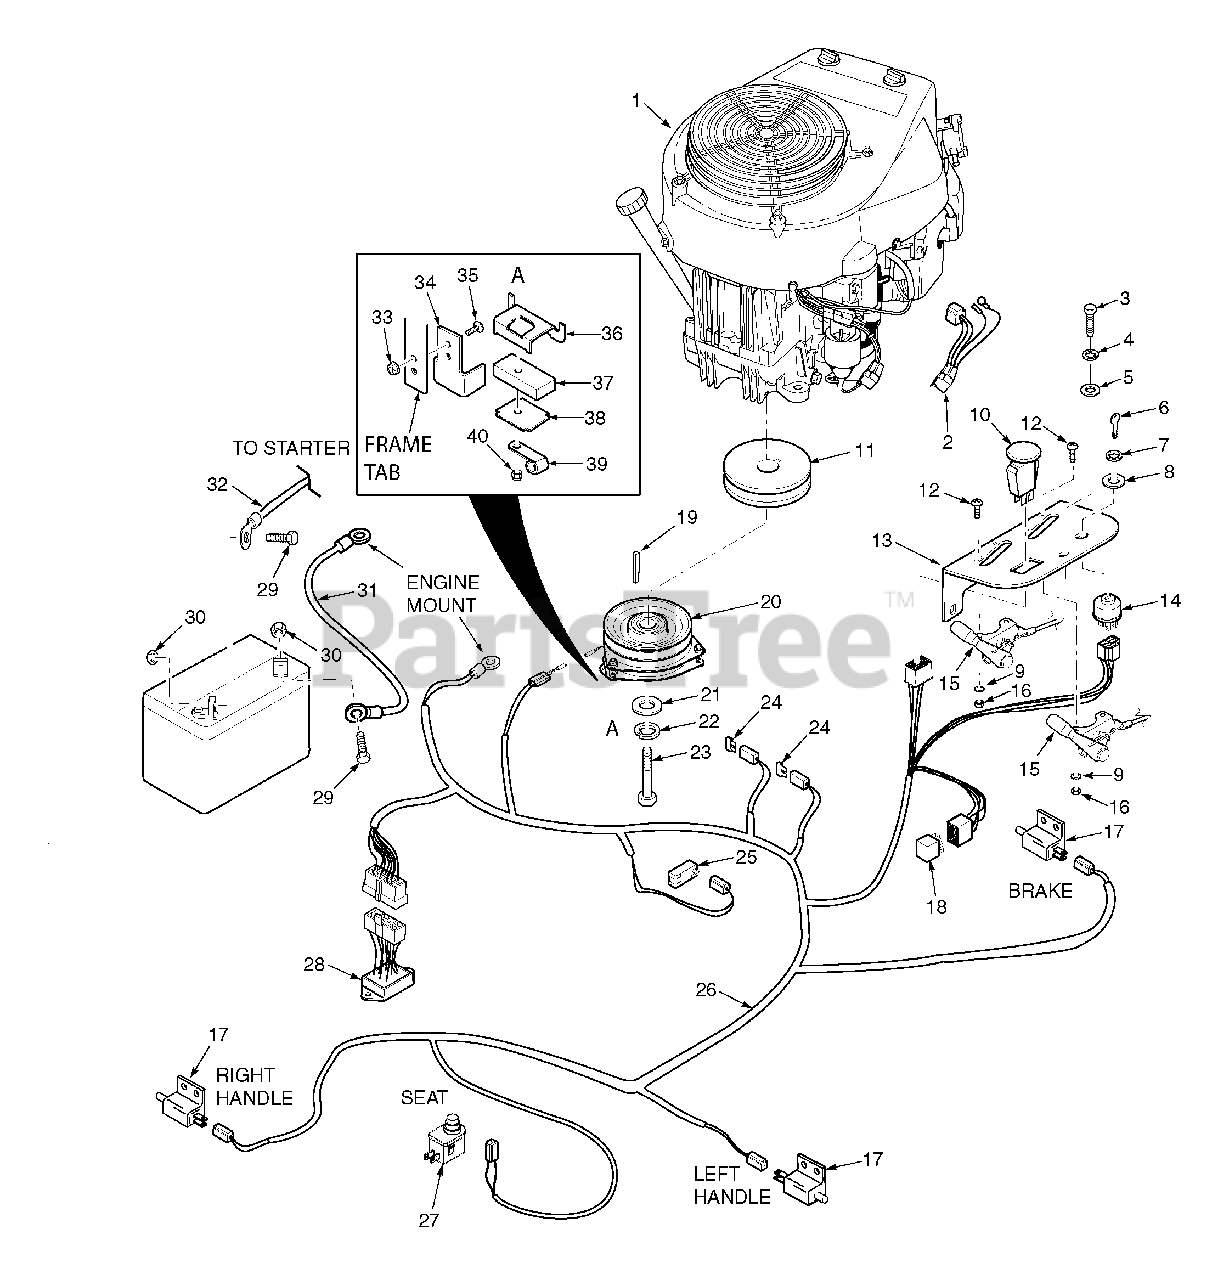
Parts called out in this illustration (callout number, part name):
1	Engine, Kawasaki 17hp (FH541V-AS36)
2	Wire Harness Adapter, SZC KA
3	Bolt, Hex Head 5/16-18 x 3/4"
4	Lockwasher, 5/16
5	Flatwasher, 5/16-.375 x .875 x .083
6	Key, Ignition
7	Nut, Hex 5/8-32
8	Lockwasher, 5/8" Internal
9	Lock Washer, #10 External Tooth
10	Switch, PTO
11	Pulley, 5.45" Dia. 1" Bore
12	Screw, #10-32 x 3/4"
13	Instrument Panel
14	Switch, Ignition
15	Control Cable
16	Nut, Hex #10-32
17	Switch, N/O
18	Relay
19	Key, 1/4 x 1/4 x 3-1/4"
20	Clutch Assembly, GT2.5 - 1" Bore
21	Flatwasher, 7/16-.469 x 1.75 x .25
22	Lockwasher, 7/16 Spring
23	Bolt, Hex Head 7/16-20 x 2-1/2" w/Patch
24	Fuse, 20 amp
25	Hourmeter
26	Wire Harness, SZC
27	Switch, Seat
28	Electric Module
29	Bolt, Hex Head 1/4-20 x .5"
30	Nut, Hex 1/4-20
31	Battery Cable, Negative Black
32	Battery Cable, Positive Red
33	Nut, Elastic Stop 5/16-18
34	Plate, Clutch Anti-Rotation
35	Bolt, Carriage 5/16-18 x 1"
36	Retainer, Clutch
37	Rubber Pad, Clutch Stop
38	Plate, Backing
39	Clamp, Cable 1/2" ID
40	Nut, Elastic Stop 5/16-18
